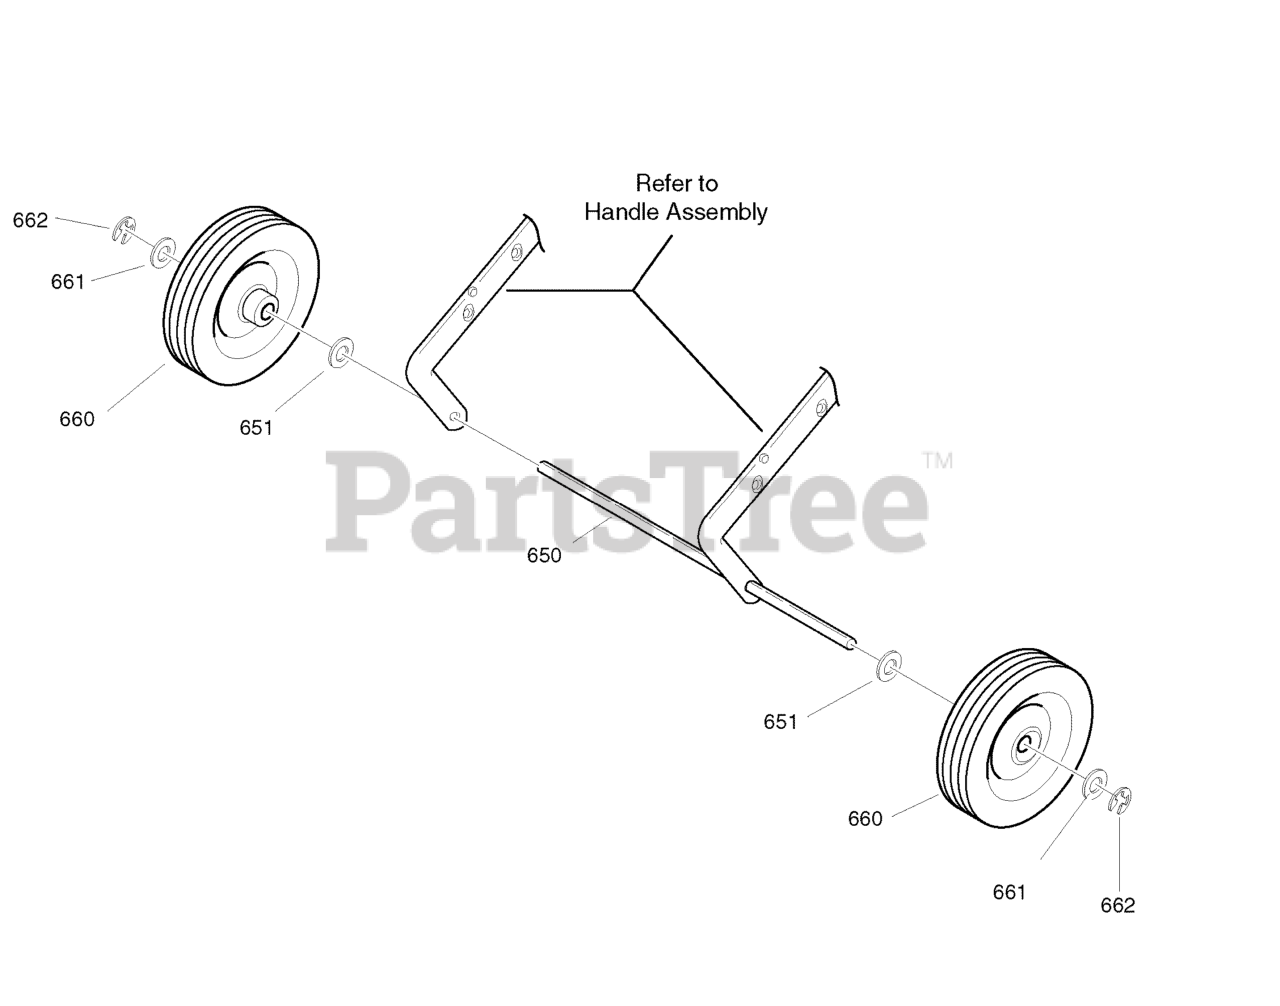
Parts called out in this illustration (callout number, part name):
650	AXLE, 20.53 WHEEL 20/21
651	WASHER, FLAT .391 X 1.00 X .125
660	TIRE & RIM 7 X 1.50
661	WASHER, FLAT .391 X 1.00 X .125
662	RING, RETAINER E
